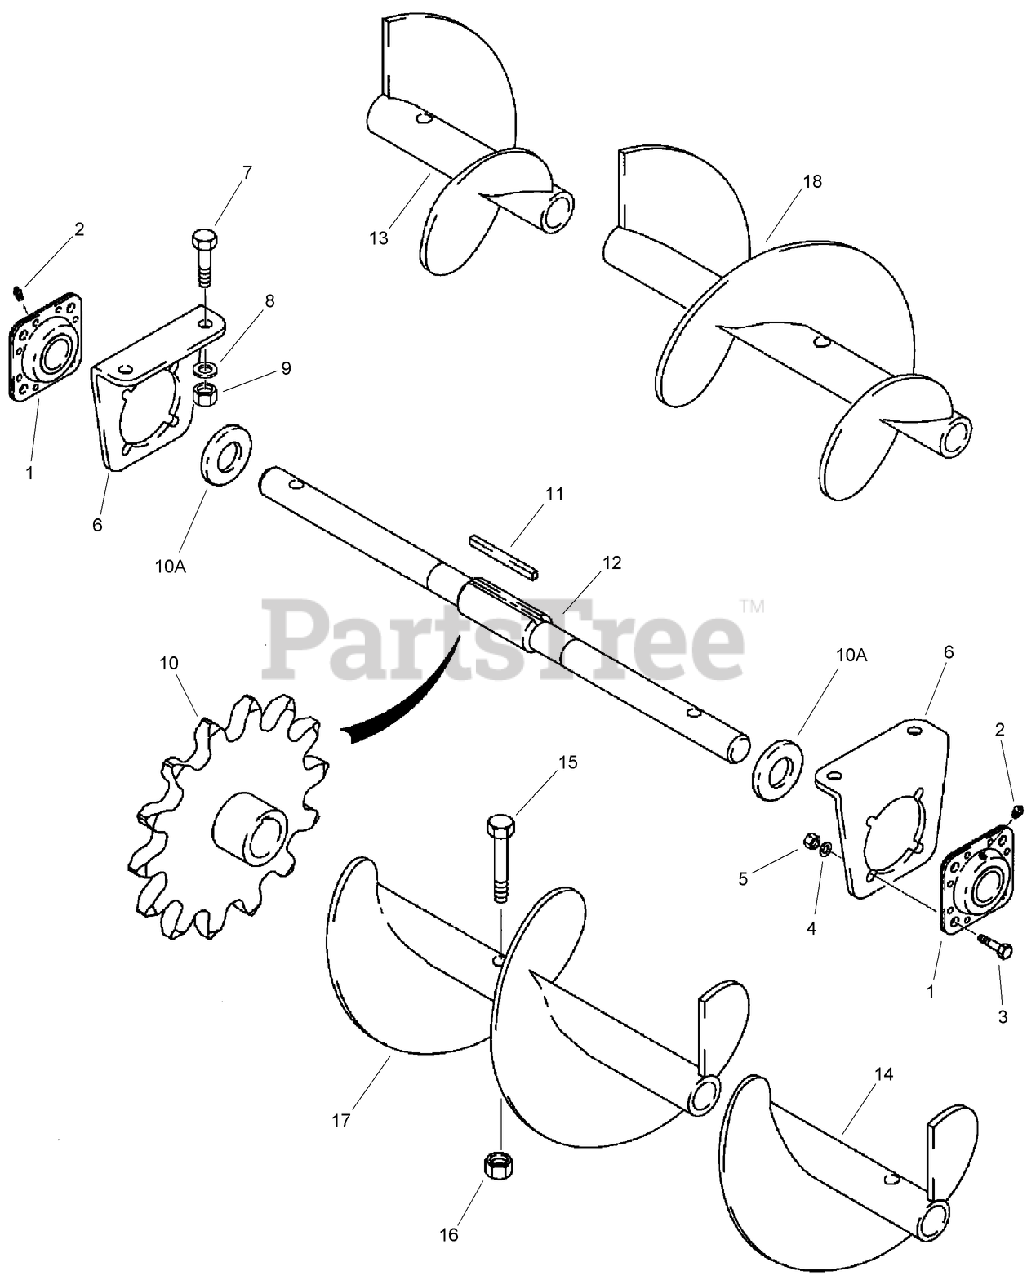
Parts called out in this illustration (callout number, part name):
1	BEARING
2	FITTING-Lube 1/8-27 Dryseal PTF
3	BOLT-Hex Hd 1/2 x 1-1/4 GR5 ZND
5	NUT-HEX
6	PLATE-mounting, auger bearing
7	BOLT-Hex Hd 0.625 x 2.00 GR8 ZND
8	WASHER-flat, special, hardened
9	NUT-LOCK, HEX
10	SPROCKET-auger drive, 14 teeth
11	KEY-SQUARE
12	SHAFT-auger
13	AUGER-spoil removal, left-hand
14	AUGER-spoil removal, right-hand
15	BOLT-hex, 3/4 NC x 3 inch, grade 8
16	NUT-Prev Trq 3/4 GRC CAD Direct
17	AUGER-spoil removal, right-hand, used instead of item 14, if used
18	AUGER-spoil removal, left-hand, used instead of item 13, if used
